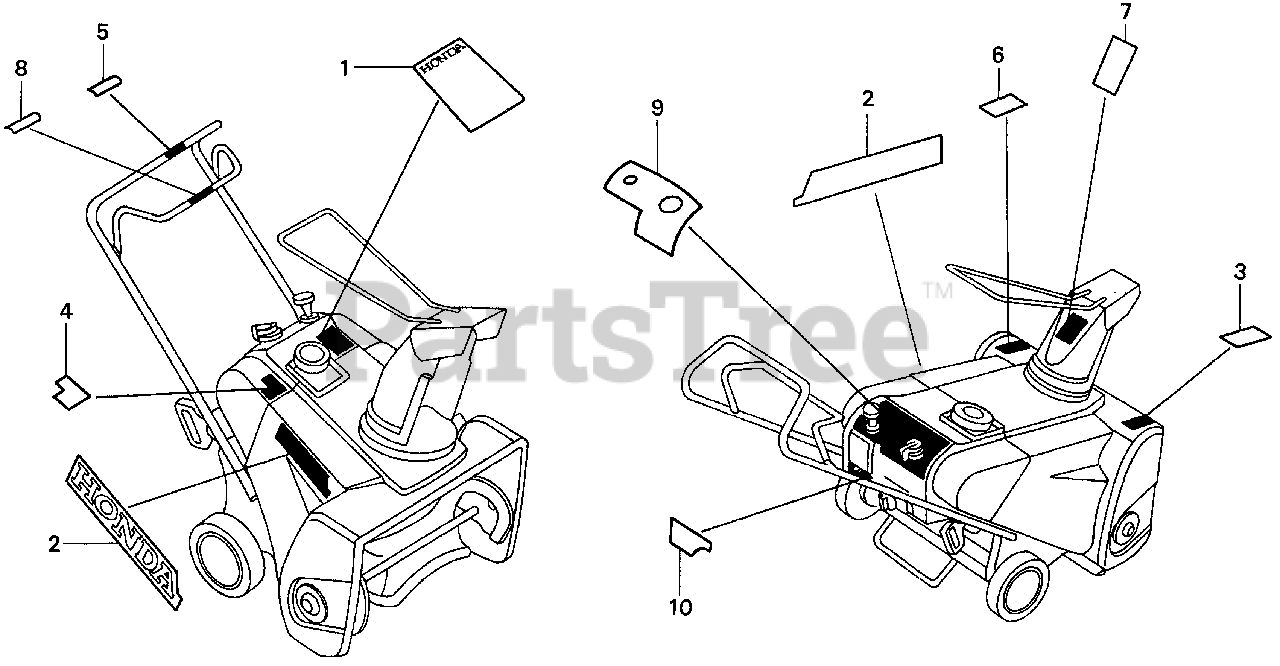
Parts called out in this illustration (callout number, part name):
1	MARK, EMBLEM
2	MARK, HONDA
3	LABEL, WARNING (ENGLISH)
4	LABEL, FUEL WARNING (ENGLISH)
5	MARK, CLUTCH OPERATION (ENGLISH)
6	MARK, HOUSING DANGER (ENGLISH)
7	MARK, DISCHARGE DANGER (ENGLISH)
8	MARK, SAFETY YELLOW
9	MARK, CONTROL OPERATION (STD)
10	LABEL, OIL CAUTION (ENGLISH)
